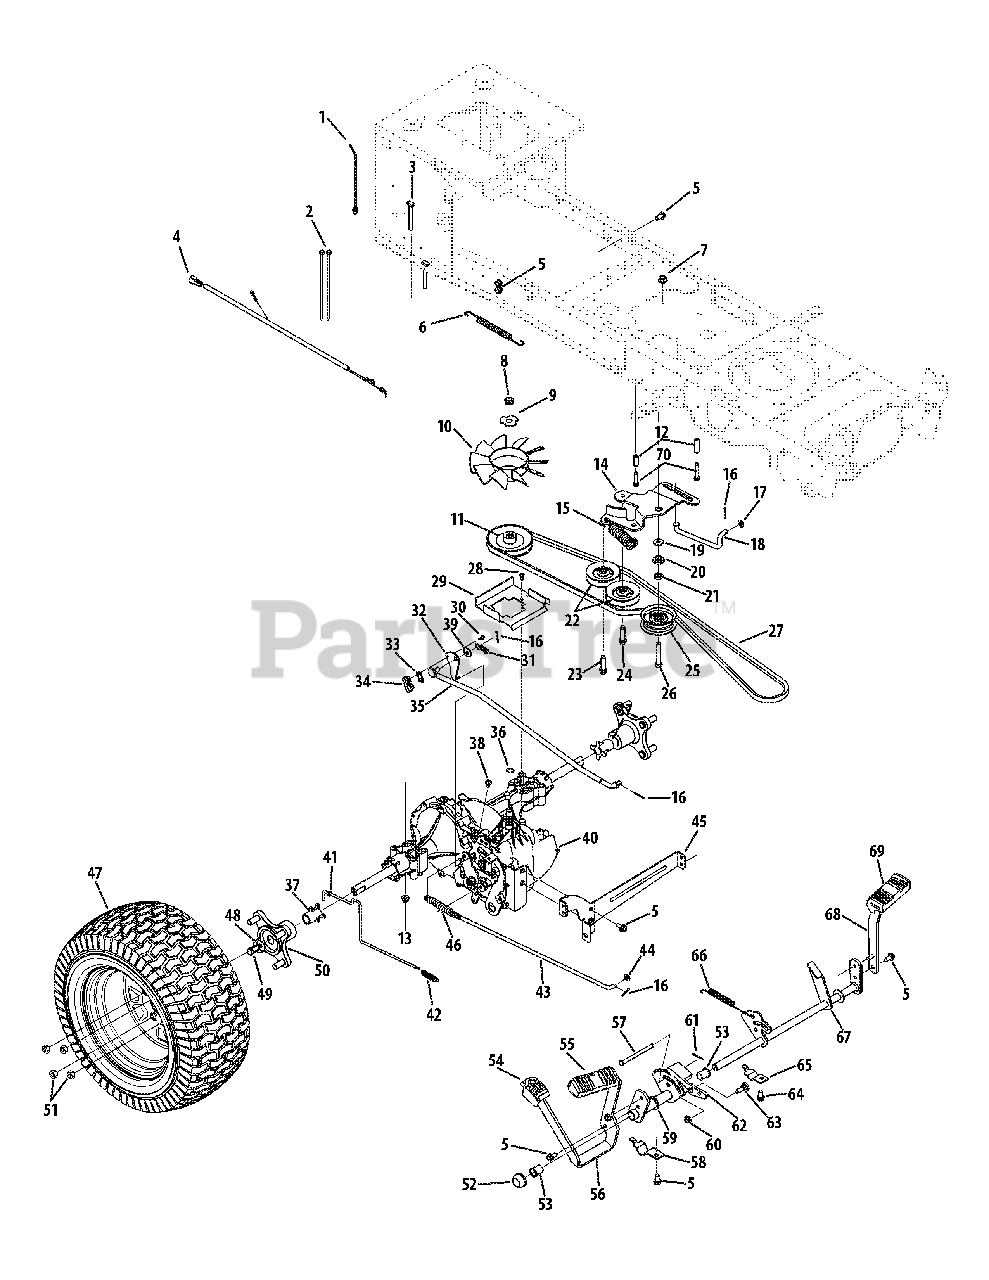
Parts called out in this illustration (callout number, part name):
1	Cable Tie, 7.5
2	Cable Tie, 3.16 x .05 x 7.4
3	Bolt, 5.16-18 x 2.75
4	Jumper Harness
5	Hex Washer Screw, 5.16-18 x .750
6	Extension Spring, .500 x 12.6
7	Flange Lock Nut, 3.8-16
8	Jam Lock Nut, 1.2-20
9	Lock Washer
11	Input Pulley
12	Spacer, .260 x .372 x 1.420
13	Flange Lock Nut, 5.16-18
14	Idler Bracket
15	Extension Spring, 1.00 x 4.75
16	Cotter Pin, 3.32 x 1.00
17	Flat Washer, .330 x .630 x .0635
18	Pedal Transmission Bypass Rod
19	Shim Washer, 1.00 x .632 x .010
20	Shoulder Spacer, 1.00 x .38 x .38
21	Jam Nut, 7.16-20
22	Idler Pulley
23	Hex Washer Screw, 3.8-16 x 1.875
24	Hex Washer Screw, 3.8-16 x 1.500
25	Idler Pulley
26	Hex Screw, 3.8-16 x 2.25
28	Screw, #10-16 x .500
29	Belt Disengage Support Bracket
30	Hex Washer Screw, #8-18 x .500
31	Extension Spring, .375 x 1.44
32	Switch Actuator Bracket
33	Nut Insulator Plate
34	Spring Safety Switch
35	Hydro Control Rod
36	Wire Ring
37	Sleeve, .765 x 2.410
38	Hex Washer Screw, 1.4-20 x .375
39	Flat Washer, .407 x .812 x .135
40	Hydro Transmission
41	Hydro Bypass Rod
42	Extension Spring, .48 x 2.03
43	Hydro Brake Rod
44	Flat Washer, .344 x .750 x .120
45	Hydro Mount Bracket
46	Extension Spring, .59 x 4.00
47	Wheel Assembly, Complete 22.0 x 9.5 x 12
48	Bell Washer, .340 x .872 x .060
49	Cap Lock Screw, 5.16-24 x .750
50	Hub Assembly
51	Lug Nut, 7.16-14
53	Flange Bearing, .630 x .695 x .60
54	Reverse Pedal Pad
55	Forward Pedal Pad
56	Forward/Reverse Hydro Pedal Bracket
57	Clevis Pin, 5.16 x 3.985
58	Transmission Rod Support Strap
59	Hydro Drive Shaft Assembly
60	Flange Lock Nut, 3.8-16
61	Bow-Tie Cotter Pin
62	Cruise Latch
63	Shoulder Bolt, 3.8-16 x .500 x .270
64	Hex Washer Screw, 5.16-18 x .625
65	Brake Shaft Support Strap
66	Extension Spring, .63 x 4.95
67	Brake Control Assembly
68	Brake Pedal Bracket
69	Brake Pedal Pad
70	Hex Washer Screw, 1.4-20 x 1.625
